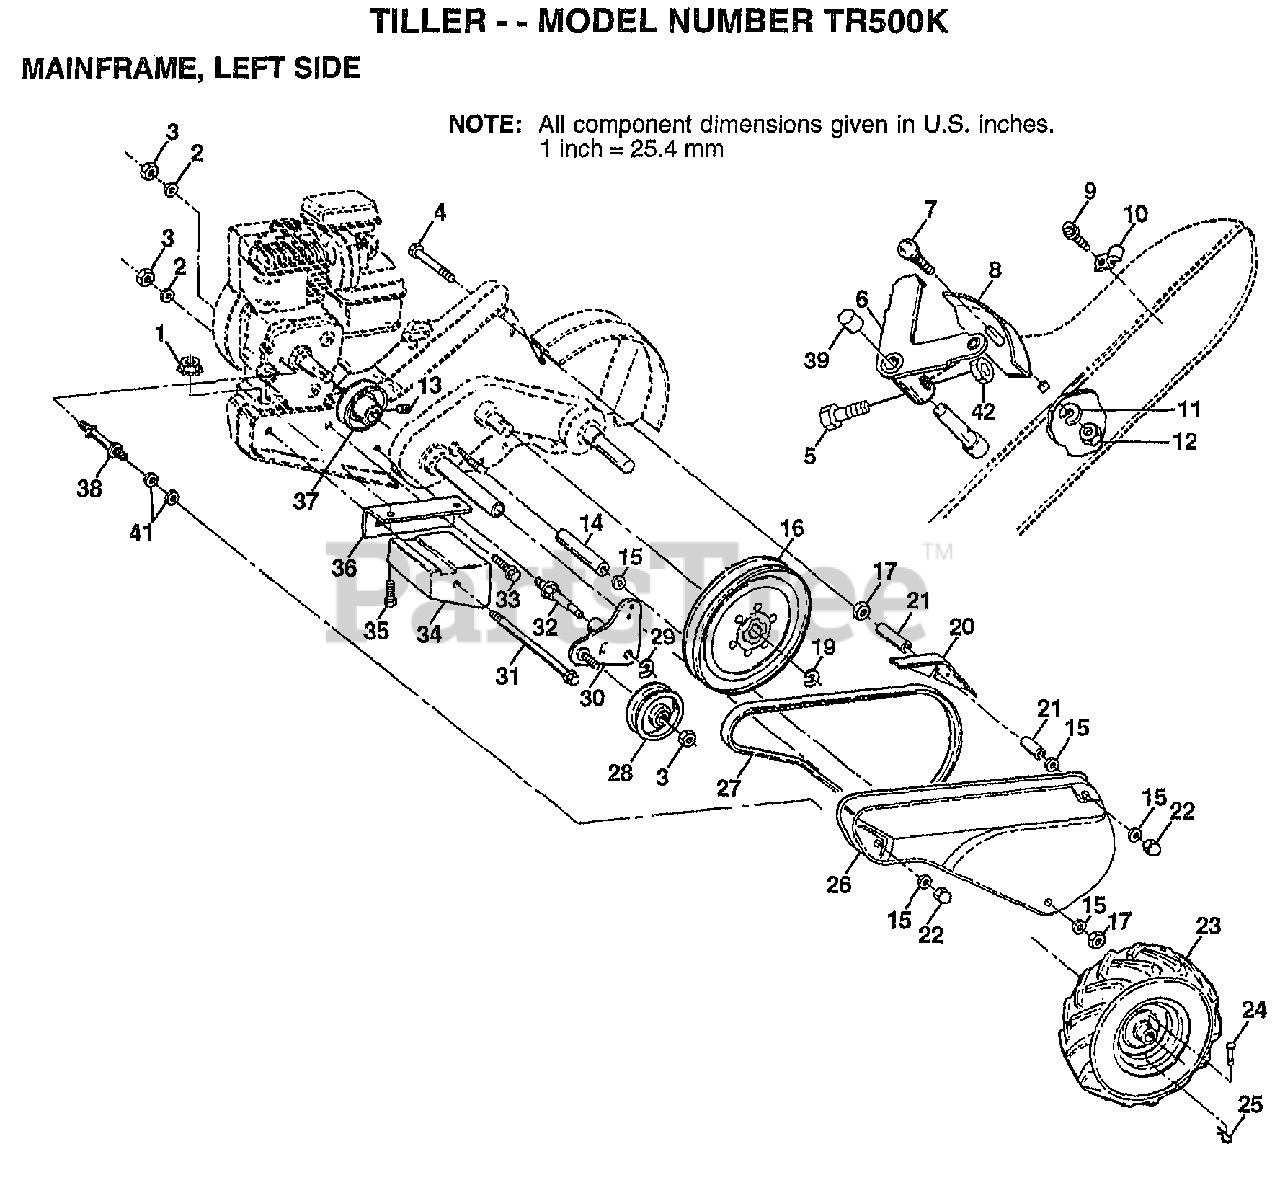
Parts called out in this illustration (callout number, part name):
2	LOCKWASHER
3	NUT.HEX.3/8-16UNC
4	BOLT TI
5	"SCREW-LEVER,SHI"
6	LEVER ASM CRT
7	BOLT
8	PANEL TI
10	CONDIUT CLIP T
11	LOCKWASHER
13	SET SCREW
14	SPACER
15	WASHER
16	SHEAVE.TRANS.
17	NUT.HEX.5/16-18
20	GUARD CRT
21	SPACER.SPLIT
22	NUT TI
23	TIRE.CHV.13X5.0-6
24	RIVET.DRILL.1.75
26	GUARD.BELT.PNT.
27	BELT-V
28	PULLEY-IDLER TI
29	KLIP RING
30	BRACKET ASM IDLER
31	BOLT CRT
32	SHIFT ARM CRT
33	BOLT
34	COUNTERWEIGHT CRT
35	BOLT.HEX.5/16-1.5
36	BRACKET LH CRT
37	ENGINE SHEAVE
38	STUD.GUARD.BELT
39	CAP PLUNGER BLACK
41	WASHER
42	LOCKNUT
